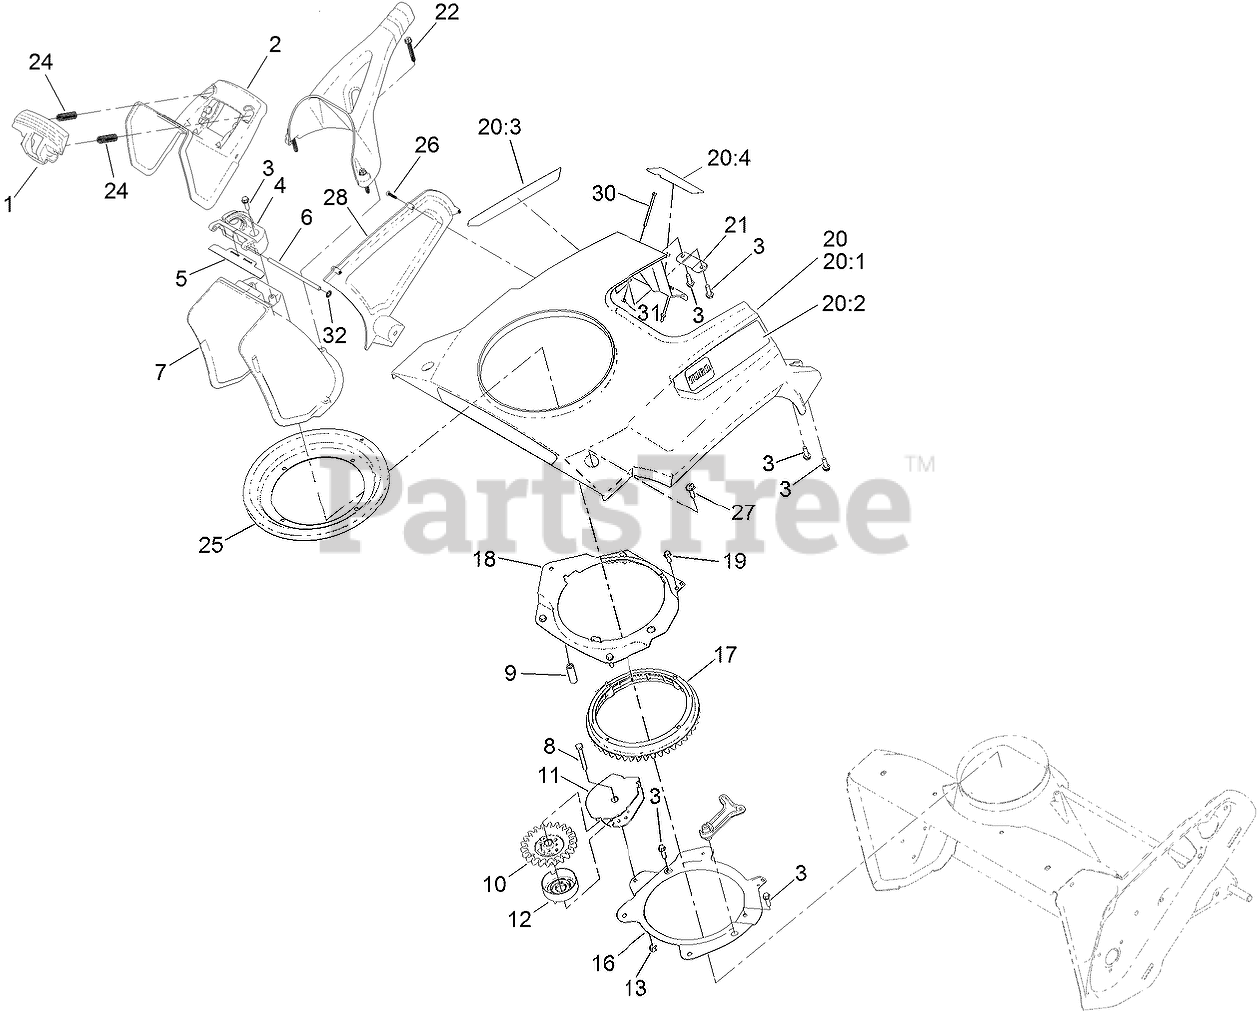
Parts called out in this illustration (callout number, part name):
1	TRIGGER-DEFLECTOR
2	DEFLECTOR-CHUTE, CE
3	SCREW-HWH
4	HINGE-RATCHET, DEFLECTOR
5	SEAL-DEFLECTOR
6	HINGE PIN-DEFLECTOR
8	SCREW-HH
9	SPACER-SLEEVE, PINION
10	PINION-GEAR
11	BRACKET-PINION
12	RETAINER-CABLE
13	NUT-LOCK, NI
16	RING-SUPPORT, CHUTE
17	RING-CHUTE, GEAR
18	RETAINER-RING, CHUTE
19	SCREW-HWH
20	SHROUD ASM, W/DECALS
20:1	SHROUD ASM, W/ARTWORK
20:2	DECAL-SHROUD LH
20:3	DECAL-SHROUD RH
20:4	DECAL-ENGINE, ELECTRIC START
21	RETAINER-SHROUD
22	SCREW-PLASTITE
24	SPRING-COMPRESSION
25	SEAL-RING, CHUTE
26	SCREW-PPH
27	SCREW-PPH
28	COVER-SIDE
30	SCREW-HWH
31	NUT-HEX
32	RING-RETAINING
